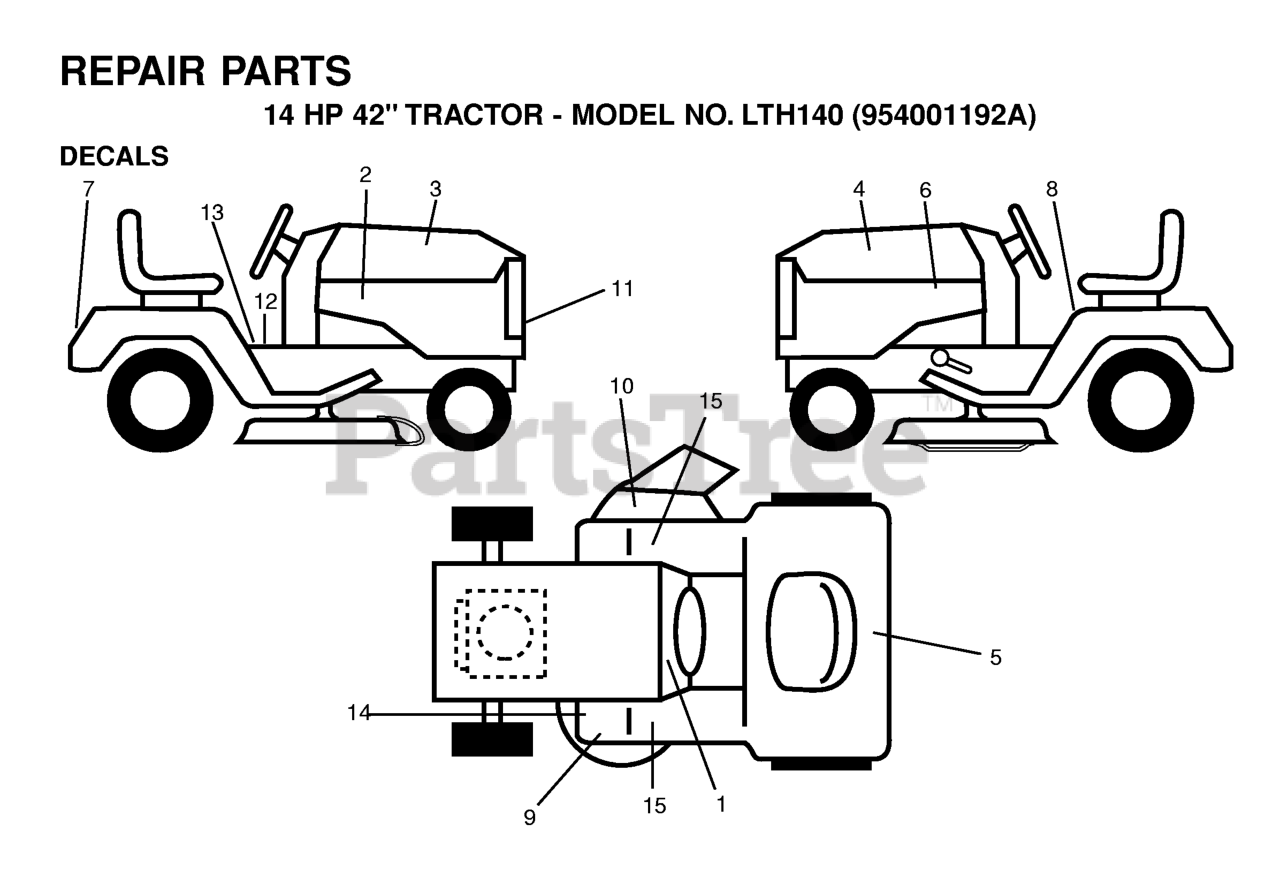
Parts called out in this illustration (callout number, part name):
3	DECAL-HOOD R.H.
4	DECAL-HOOD L.H.
7	DECAL FENDER NLA
8	DECAL CAUTION
10	DECAL WARNING (ENGLISH/FRENCH)
11	DECAL GRILL HUSQ NLA
13	DECAL PARK BRAKE
14	DECAL V-BELT SCHEMATIC
15	PAD FOOTREST T
